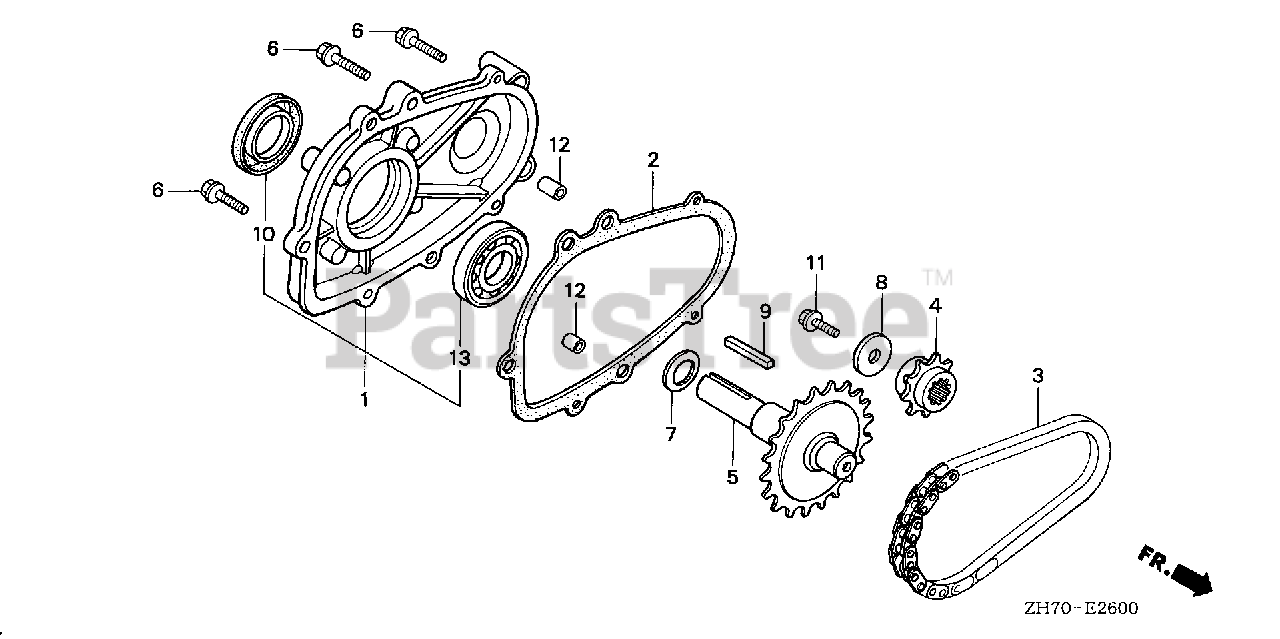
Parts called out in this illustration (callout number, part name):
1	COVER ASSY., CHAIN CASE
2	GASKET, CHAIN CASE COVER
3	CHAIN, P.T.O. DRIVE (DID270S-DHA-36LE)
4	SPROCKET, DRIVE (14T)
5	SHAFT, P.T.O. (28T)
6	BOLT, FLANGE (6X28) (CT200)
7	SPRING, THRUST
8	WASHER (8MM)
9	KEY (5X5X33) (YELLOW)
10	OIL SEAL (25X41X6) (NOK)
10	OIL SEAL (25X41X6)
11	BOLT, HEX. (8X25)
12	PIN, DOWEL (8X14)
13	BEARING, RADIAL BALL (6205)
